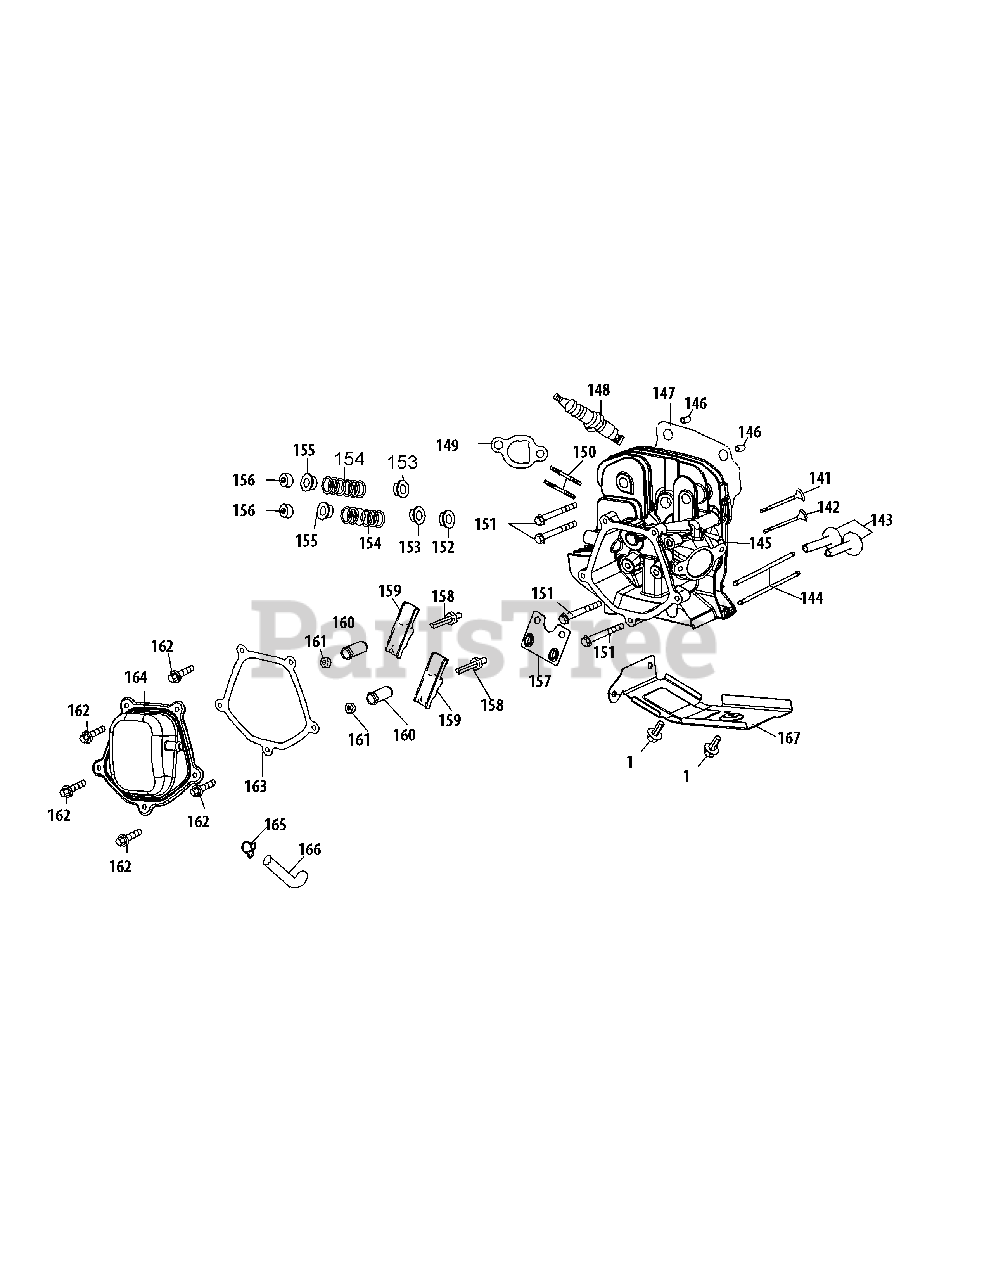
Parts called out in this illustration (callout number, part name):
1	BOLT M6×12
141	EXHAUST VALVE
142	INTAKE VALVE
143	TAPPET
144	PUSH ROD
145	CYLINDER HEAD
146	DOWEL PIN 12×20
147	GASKET, CYLINDER HEAD
148	SPARK PLUG/F6RTC
149	EXHAUST PIPE GASKET
150	STUD M8×48.5
151	BOLT M10×1.25×80
152	VALVE SEAL (INTAKE)
153	VALVE SPRING RETAINER(INTAKE)
154	VALVE SPRING
155	VALVE SPRING RETAINER
156	EXHAUST LASH CAP
157	PUSH ROD GUIDE
158	BOLT, PIVOT
159	ROCKER ARM
160	ADJUSTING NUT ,VALVE
161	NUT, PIVOT LOCKING
162	VALVE COVER BOLT
163	VALVE COVER GASKET
164	VALVE COVER
165	BREATHER HOSE CLAMP
166	BREATHER HOSE
167	AIR SHIELD
